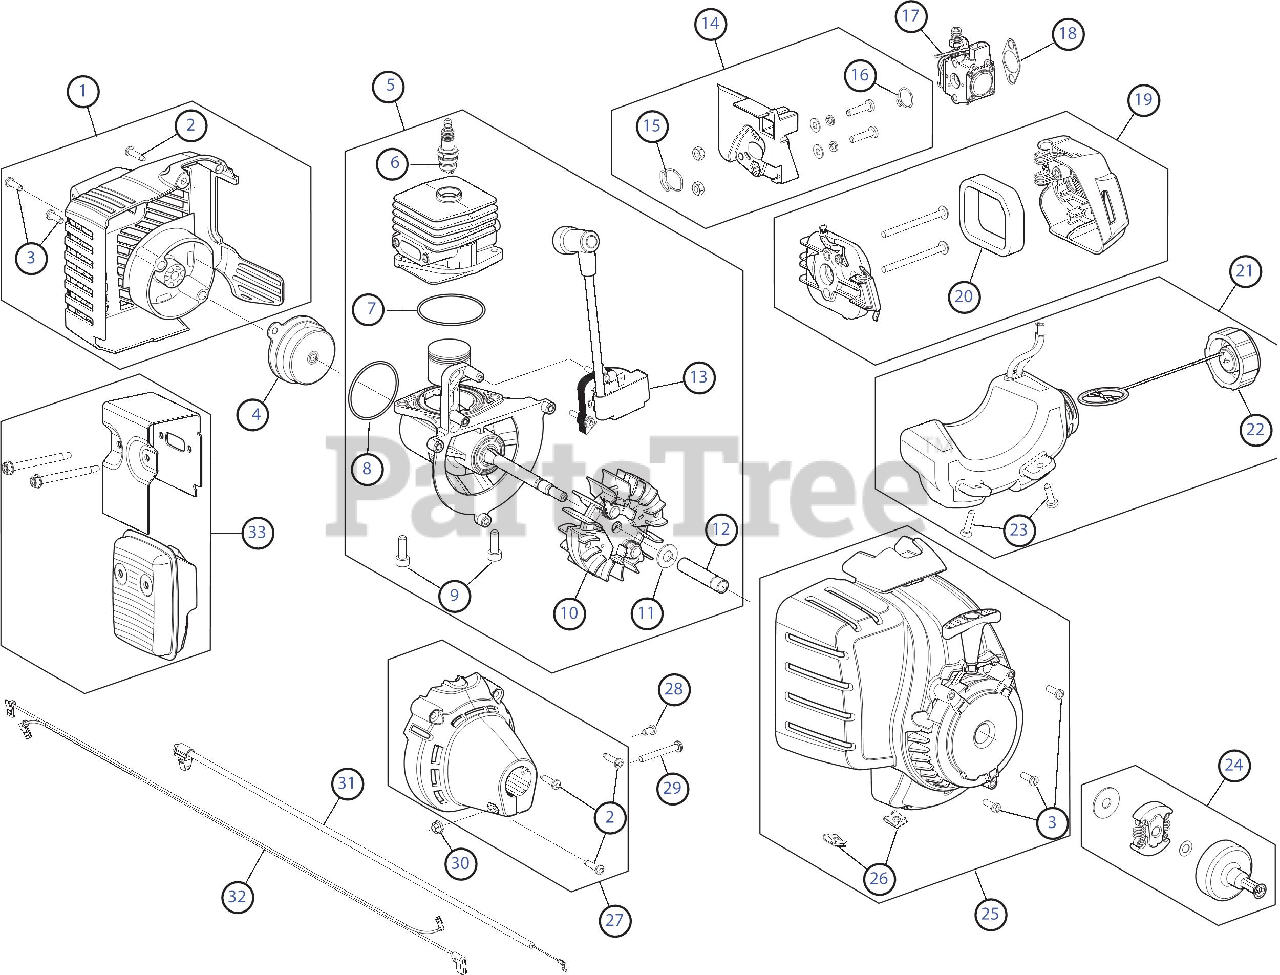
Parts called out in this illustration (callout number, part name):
1	Rear Cover Assembly
2	Cover Screw
3	Rear Housing Screw
4	Electric Start Cover Assembly
5	Short Block Assembly
6	Spark Plug
7	Crankcase O-Ring
8	O-Ring
9	Crankcase Bolt
10	Flywheel Assembly
11	Washer
12	Spacer
13	Module Assembly
14	Insulator Assembly
15	Insulator O-Ring
16	Carburetor O-Ring
17	Carburetor
18	Air Cleaner Gasket
19	Air Cleaner Cover Assembly
20	Air Cleaner Filter
21	Fuel Tank Assembly
22	Fuel Tank Cap
23	Fuel Tank Screw
24	Clutch Assembly
25	Starter Housing
26	U-shaped Nut
27	Clutch Cover
28	Anti-rotation Screw
29	Clamp Screw
30	Clamp Nut
31	Throttle Cable
32	Lead Wires
33	Muffler Assembly
